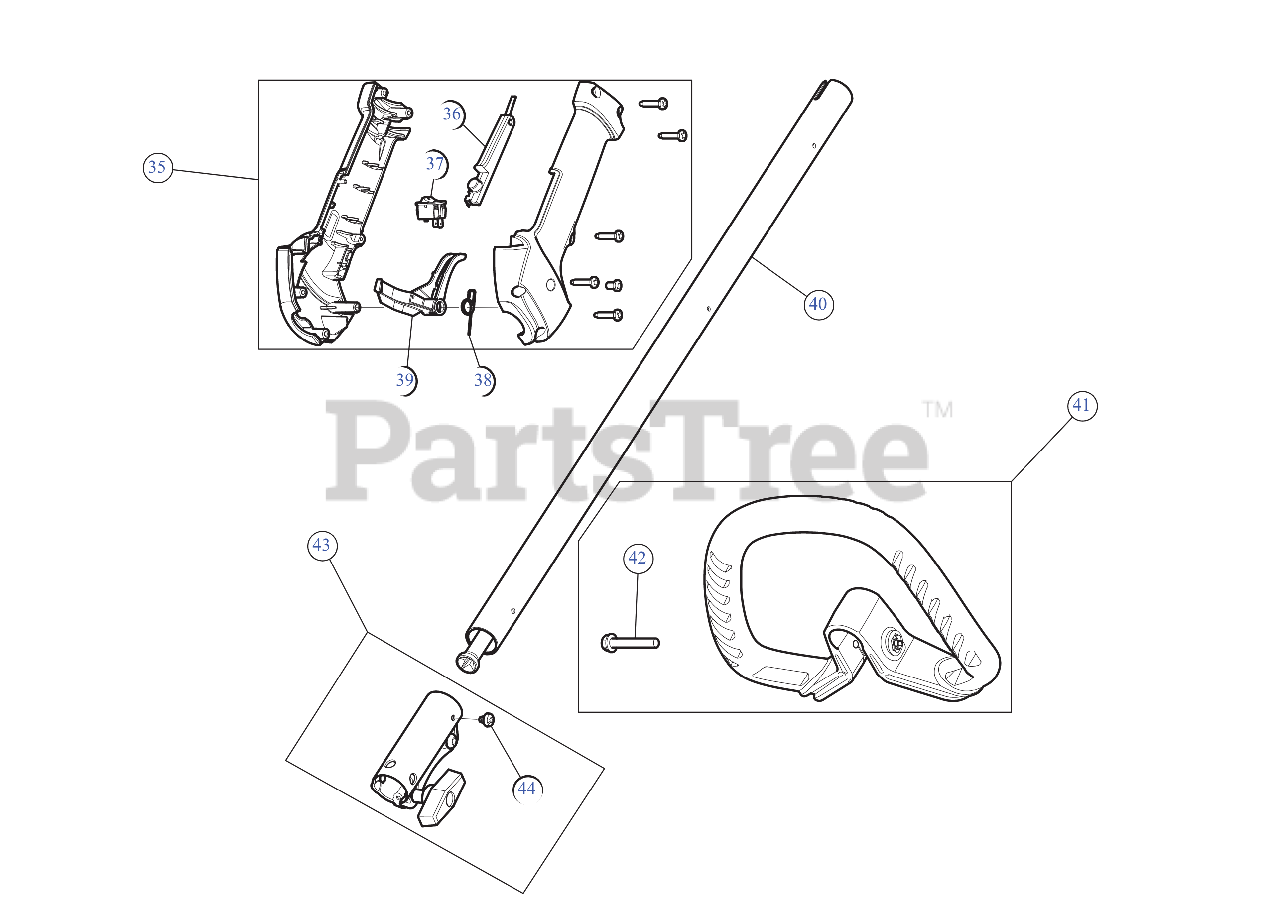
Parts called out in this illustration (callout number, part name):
35	THROTTLE GRIP ASSEMBLY
36	LEVER LOCK OUT
37	SW, MOMENTARY ON/O
38	SPRING TRIG
39	THROTTLE TRIGGER
40	BOOM ASSEMBLY UPR
41	HANDLE ASSEMBLY
42	BOLT 1/4-20X1 1/2
43	COUPLER ASSEMBLY
44	SCREW, 10-32X.250 TA
